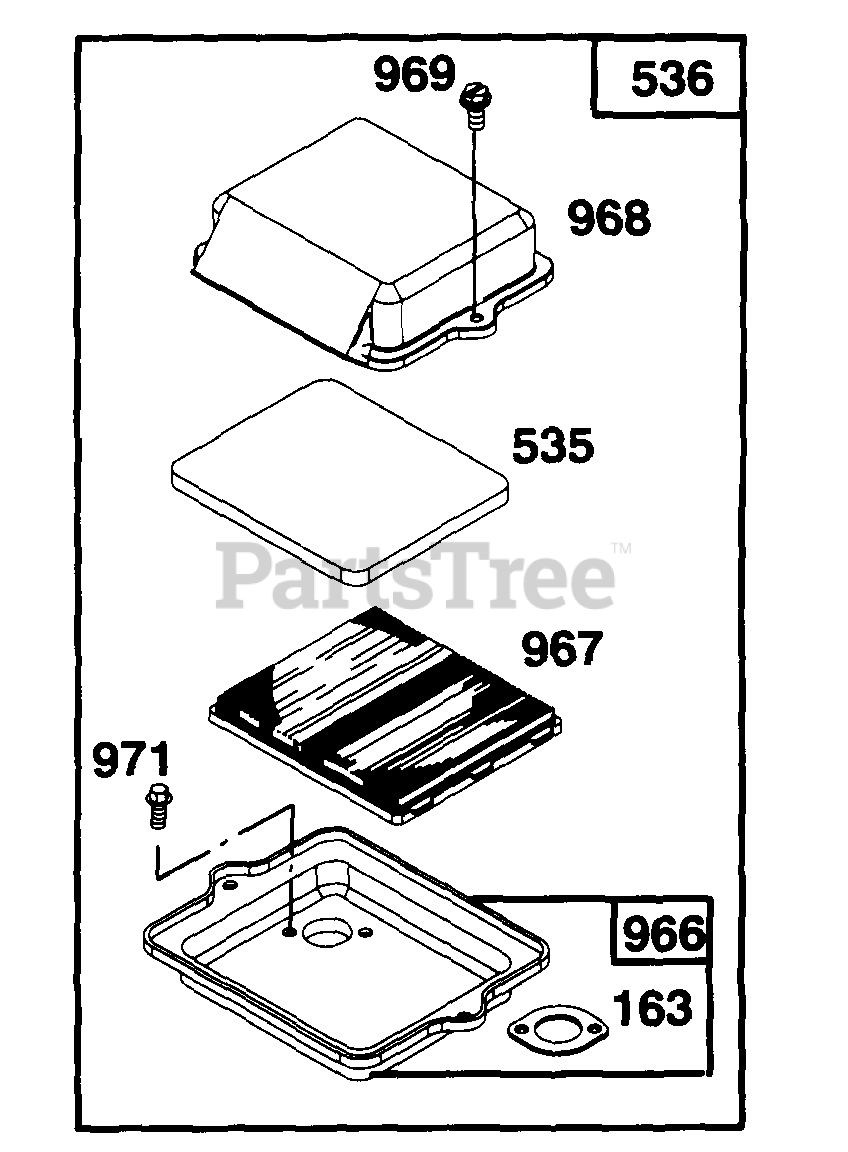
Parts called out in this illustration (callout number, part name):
163	Gasket-Air Cleaner
535	Element-Air Cleaner
536	Air Cleaner Kit
966	Base-Air Cleaner
967	Filter-Air
968	Cover-Air Cleaner
969	Screw-Cover Mtg.
971	Screw-Air Cleaner
